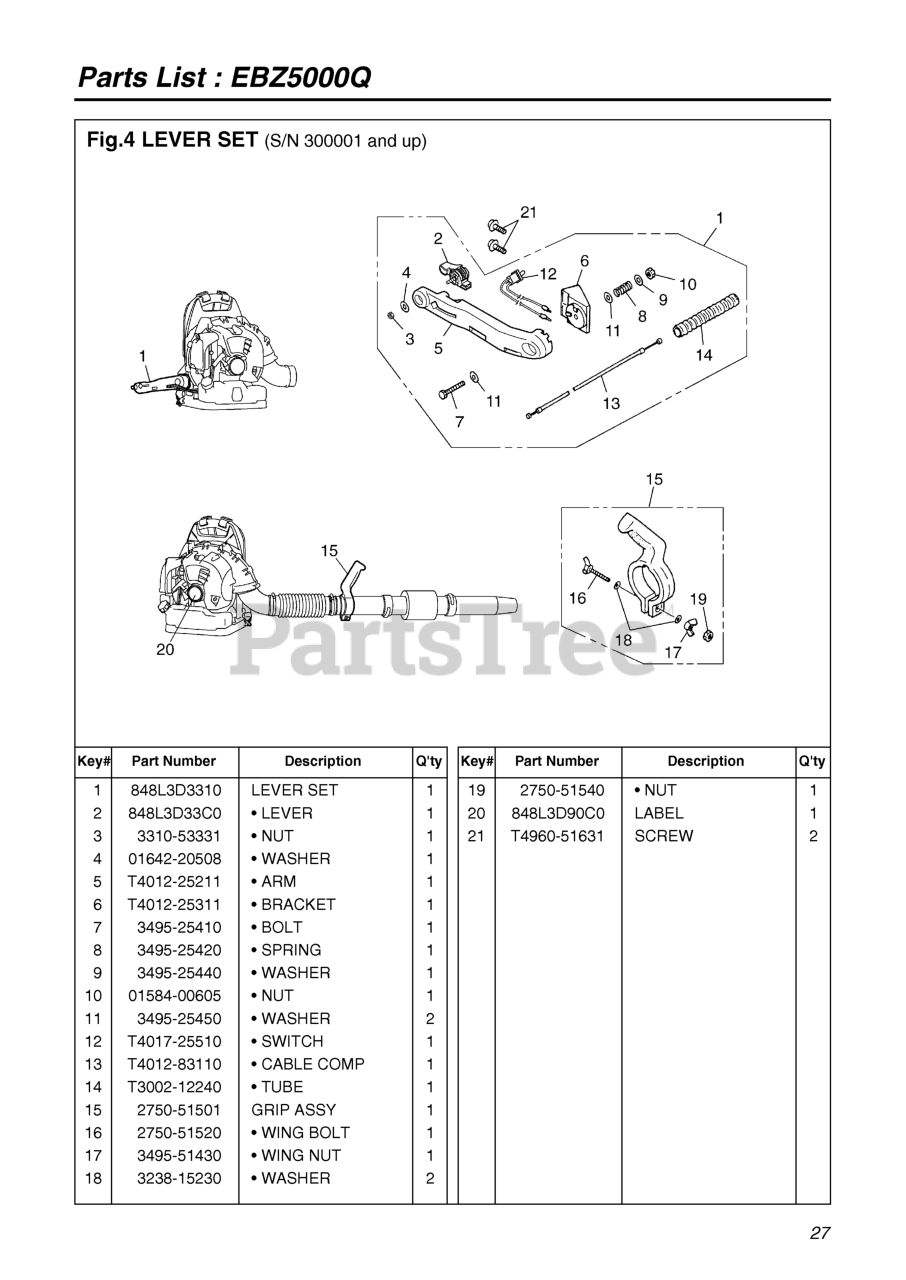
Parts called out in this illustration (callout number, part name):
1	LEVER SET
3	NUT (B)
4	WASHER, M5x.8(RPLS 01624-20508
5	ARM (RPLS T4012-25210)
6	BRACKET (RPLS -25310)
7	BOLT
8	SPRING
9	WASHER
10	NUT, M6 X 5
11	WASHER, FLAT
12	SWITCH
13	CABLE COMPLETE
14	TUBE (RPLS 4900-72141)
15	GRIP ASSEMBLY (RPLS -51500)
16	WING BOLT
17	NUT, WING
18	WASHER
19	NUT
20	LABEL, RECOIL (EBZ5000Q)
21	SCREW TORX
